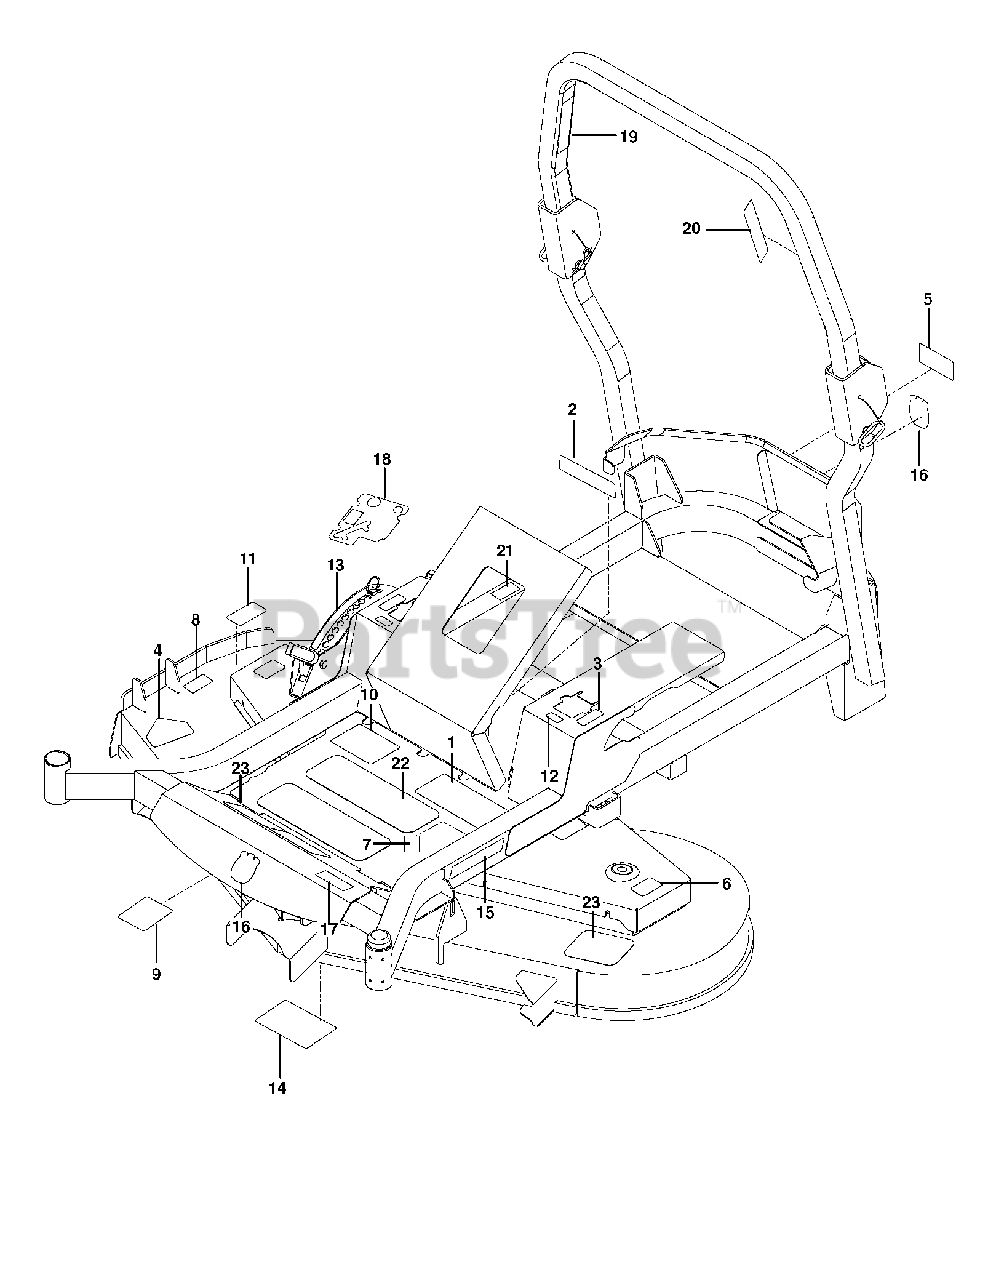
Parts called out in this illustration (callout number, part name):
1	DECAL, WARNING
2	EURO DECAL-BATTERY WARNIN6
3	DECAL, MOTION CONTROL
4	DECAL, CPSC
5	DECAL, BELT DRIVE
6	DECAL.DECK.6MIL.EURO.NOSTEP
7	DECAL.80.DBA.AUSTRALIA
8	DECAL, EURO SEVERING
9	DECAL, BELT ROUTING
10	DECAL, WARNING
11	DECAL.DECK.6MIL./DEF.SHLD.WARN
12	DECAL, F.S.T.
13	DECAL, HEIGHT ADJUST
14	DECAL, SERVICE
15	RP.DECAL.BADGE.170MM.TEXTLOGO
16	DECAL.AUGER.HUSQ.CROWN.SNOW
17	DECAL ZTR MZT61 HUSQVARNA
18	DECAL, CONSOLE HUS
19	DECAL, ROPS, WARNING
20	DECAL ROPS
21	DECAL, ECM, AUSTRALIA
22	ANTI-SKID PAD
